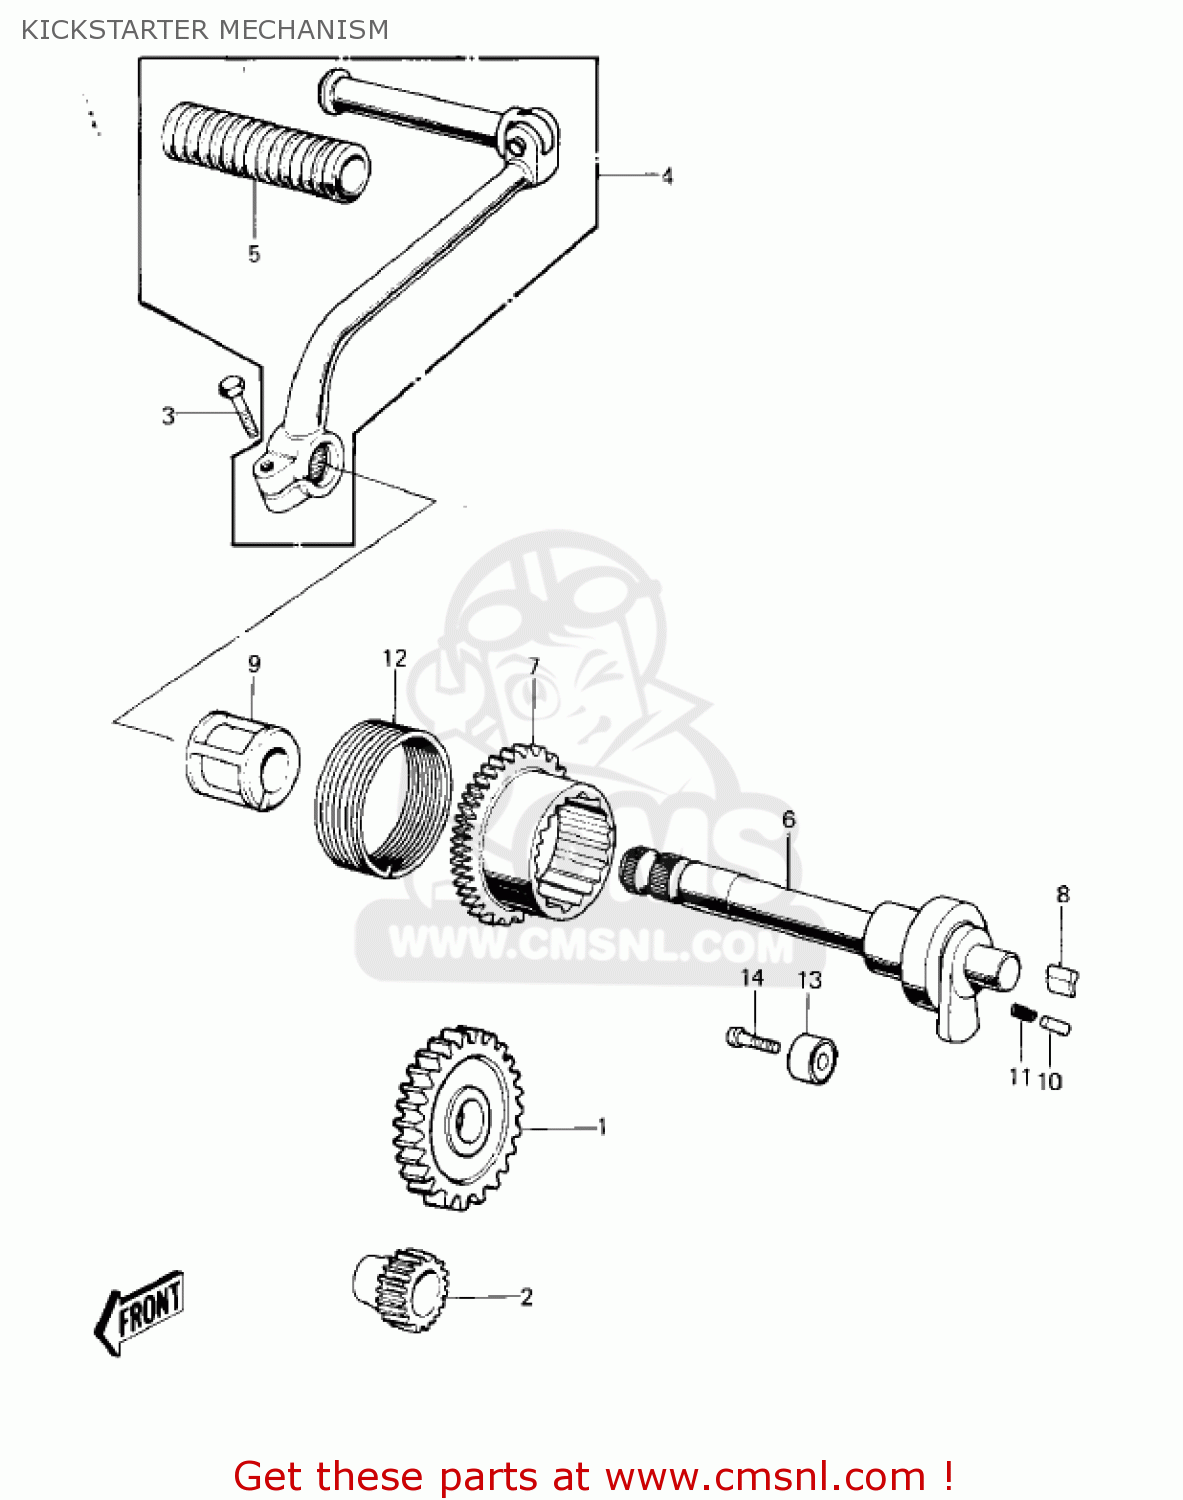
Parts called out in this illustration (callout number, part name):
1	GEAR-SPUR,KICKSTARTER
2	GEAR-SPUR,KICKSTARTER
3	BOLT-HEX,HEAD,8X25
4	PEDAL,KICKSTARTER
5	RUBBER-KICK PEDAL
6	SHAFT-KICK
7	GEAR-SPUR,KICKSTARTER
8	PAWL,KICKSTARTER
9	GUIDE,KICK SPRING
10	PIN,DOWEL,3.9X10.8
11	SPRING-KICK PAWL
12	SPRING-KICKSTARTER
13	STOPPER,KICKSTARTER
14	SCREW-CNTSNK HD,6X20
